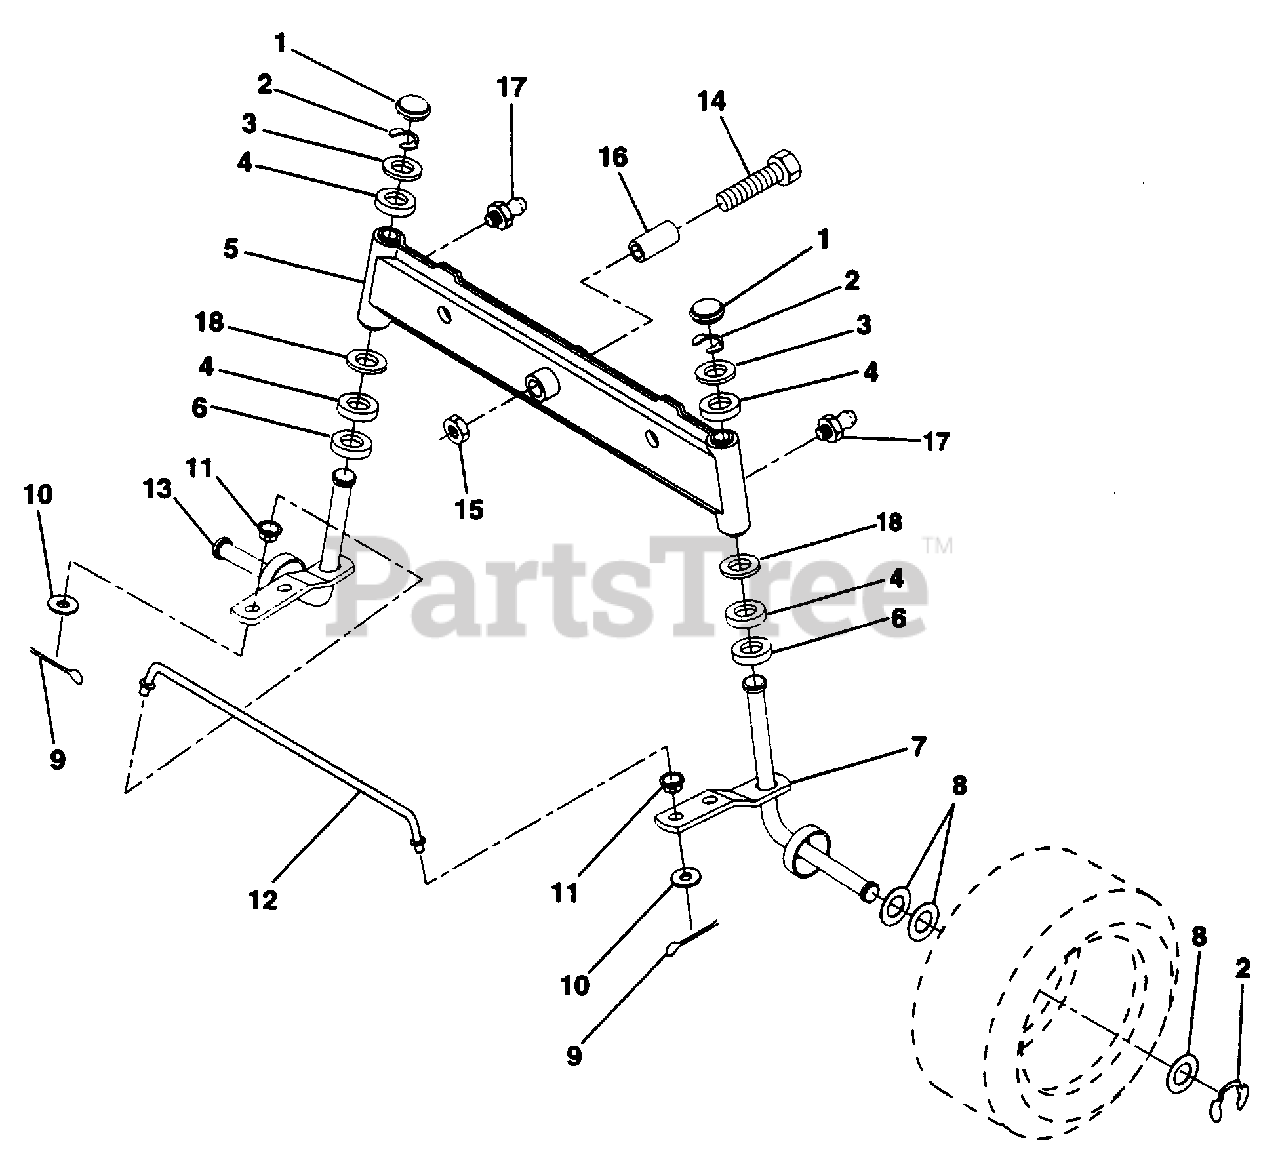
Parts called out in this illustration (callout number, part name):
1	Cap, Spindle (AYP part number)
2	Ring, Clip (AYP part number)
3	Washer 25/32 x 1-5/8 x 16 Ga. (AYP part number)
4	Nyliner (AYP part number)
5	Axle, Front (AYP part number)
6	Bearing, Thrust (AYP part number)
7	Spindle, R.H. Asm.
8	Washer 25/32 x 1-1/4 x 16 Ga. (AYP part number)
9	Pin, Cotter 1/8 x 3/4 (AYP part number)
10	Washer 13/32 x 13/16 x 16 Ga. (AYP part number)
11	Bushing (AYP part number)
12	Rod, Tie (AYP part number)
13	Spindle, L.H. Asm. (AYP part number)
14	Bolt Hex 5/1-11 x 3-1/2 (AYP part number)
15	Nut, Lock Flange 5/8-11 (AYP part number)
16	Spacer, Bearing Axle (AYP part number)
17	Fitting, Grease (AYP part number)
18	Washer 27/32 x 1-1/4 x 16 Ga. (AYP part number)
